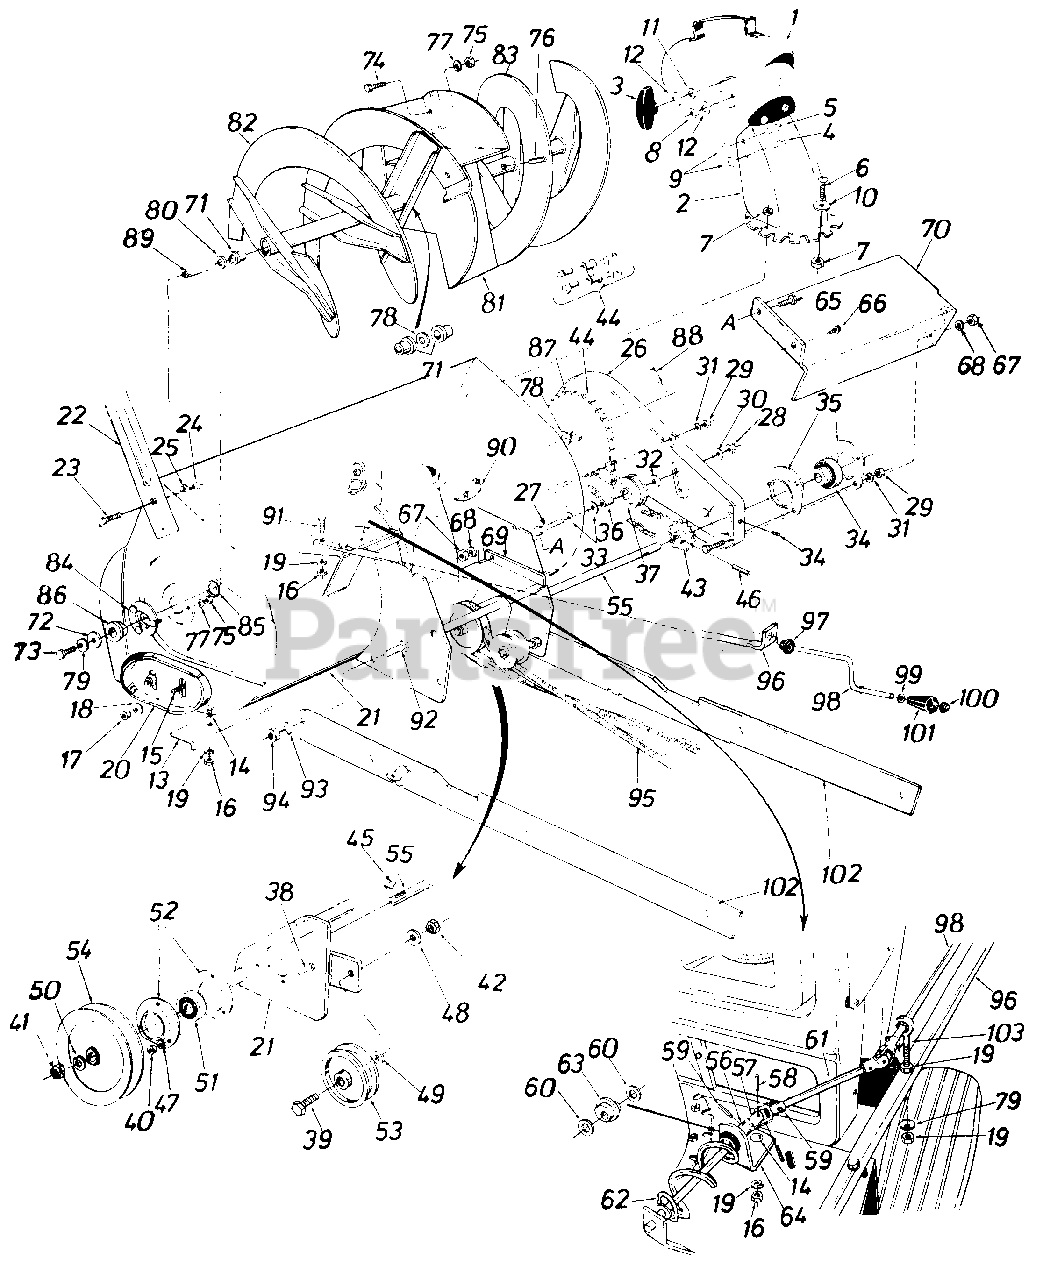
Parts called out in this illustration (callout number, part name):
1	Top Chute Ass'y.
2	Chute Ass'y. w/Guard
3	Knob Handle Ass'y.
4	Carriage Bolt 5/16-18 x .62" Lg.
5	Carriage Bolt 5/16-18 x 1.0" Lg.
6	Truss Mach. Scr. 1/4-20 x .50" Lg.
7	Hex Cent. L.-Nut 1 /4-20 Thd.
8	Hex Cent. L-Nut 5/16-18 Thd.
9	Fl.-Wash. .531" I.D. x 1.25" O.D.
10	Fl.-Wash. .285" I.D. x 1 25" O.D
11	Fl. Wash. .344" I.D. x I.D. x 1.125" O.D.
12	Bell.-Wash. .345" I.D. x .88" O.D.
14	Carriage Bolt 5/16-18 x .62" Lg.
15	Carriage Bolt 3/8-16 x .62" Lg.
16	Hex Nut 5/16-18 Thd.
17	Hex Jam Nut 3/8-16 Thd.
18	Bell. Wash. .400" I.D. x .88" O.D.
19	L.-Wash. 5/16" I.D.
20	Slide Shoe
21	Spiral Hsg. Ass'y.-36"
22	Guide Blade
23	Carriage Bolt 5/16-18 x .62" Lg.
24	Hex Nut 5/16-18 Thd.
25	L.-Wash. 5/16" I.D.
26	Chain Guard Ass'y.
27	Hex Bolt 3/8-16 x 2.00 Lg.
28	Hex Inst.-Nut 3/8-16 Thd.
29	Hex Nut 5/16-18 Thd.
30	Bell.-Wash. .400" I.D. x .88 O.D.
31	L.-Wash. 5/16" I.D.
32	Fl.-Wash. .406" I.D. x 1.25" O.D.
33	Fl.-Wash. .385" I.D. x .87" O.D.
34	Ball Brg. .75" I.D.
35	Flangette
36	Spacer .375" I.D. x .60" O.D.
37	Fl.-Idler w/Flanges 2.0" O.D. Plastic
38	Hex Sems Bolt 5/18 x .75" Lg.
39	Hex Bolt 3/8-16 x 1.75" Lg.
40	Hex Nut 5/16-18 Thd.
41	Hex Jam Nut 3/4-10 Thd.
42	Hex Jam Nut 3/8-16 Thd.
43	Sprocket Ass'y. 14 Teeth
44	#420 Chain x 112" Pitch 78 Links
45	#61 Hi-Pro-Key 3/16 x 5/8" Dia.
46	Spring Pin Spir. 5/16" Dia. x 1.75" Lg.
47	L.-Wash. 5/16" I.D.
48	L.-Wash. 3/8" I.D.
49	Fl.-Wash. .406" I.D. x 1.25" O.D.
50	Spring L.-Wash. 3/4" I.D.
51	Self-Aligning Brg.
52	Flangette
53	Idler Pulley
54	5/8 V Pulley .75" I.D. x 6.0" O.D.
55	Drive Shaft Ass'y.
56	Joint Brkt. Ass'y.
57	Joint Block
58	Spring Pin Spir. 3/16 Dia. x 1.0" Lg.
59	Spirol Pin-1/8" Dia. x .812" Lg.
60	Fl.-Wash. .385" I.D. x .62" O.D.
61	Chute Crank Ext. Rod 3/8" Dia. x6.0" Lg.
62	Chute Crank Ass'y. R.H. 6-1/4" Lg.
63	Plastic Bushing .380 I.D.
64	Chute Crank Brkt.
65	Hex Bolt 1/4-20 x .62" Lg .
66	Hex Wash. S-Tap Scr. 1/4-20 x .50" Lg.
67	Hex Nut 1/4-20 Thd.
68	L.-Wash. 1/4..I.D.
69	Belt Cover
70	Drive Shaft Cover
71	Plastic Bushing
72	Washer .39" I.D. x 1.75" O.D.
73	Hex Bolt 5/16-18 x .88" Spec.
74	Carriage Bolt 5/16-18 x x .75" Lg.
75	Hex Nut 5/16-18 Thd.
76	Spring Pin Spir. 5/16" Dia. x 1. 75" 1 Lg.
77	L.-Wash. 5/16" I.D.
78	Truss Wash. 1.03" I.D. x 1.62" O.D.
79	Bell.-Wash. .345" I.D. x .88" O.D.
80	Fl.-Wash. 1.0" I.D. xl.75" O.D.
85	Snap R ing for 1. 50" Shaft
86	Flange Brg. w/flats 1.00" I.D.
87	Sprocket Hub Ass'y. 40 Teeth
88	Spring Pin Spir 5/16 Dia. x 1.75" Lg.
89	Spiral Axle
90	Chute Flange Keeper Ass'y.
91	Hex Bolt 5/16-18 x 1.5" Lg.
92	Hex Bolt 1/2-13 x 1.25" Lg.
93	L.-Wash. 112" I.D.
94	Hex Nut 1/2"-13 Thd.
95	"V"-Belt 1/2" "A" x 89.0" Lg.
98	Chute Crank .375" Dia. x 33.0" Lg.
99	Fl.-Wash..35" I.D. x .62" O.D.
100	Push Nut 3/8" Rod
101	Knob Black 3/8" Dia. Hole
102	Linkage Arm
103	Eye Bolt 5/16-18 x 3.0" Lg.
